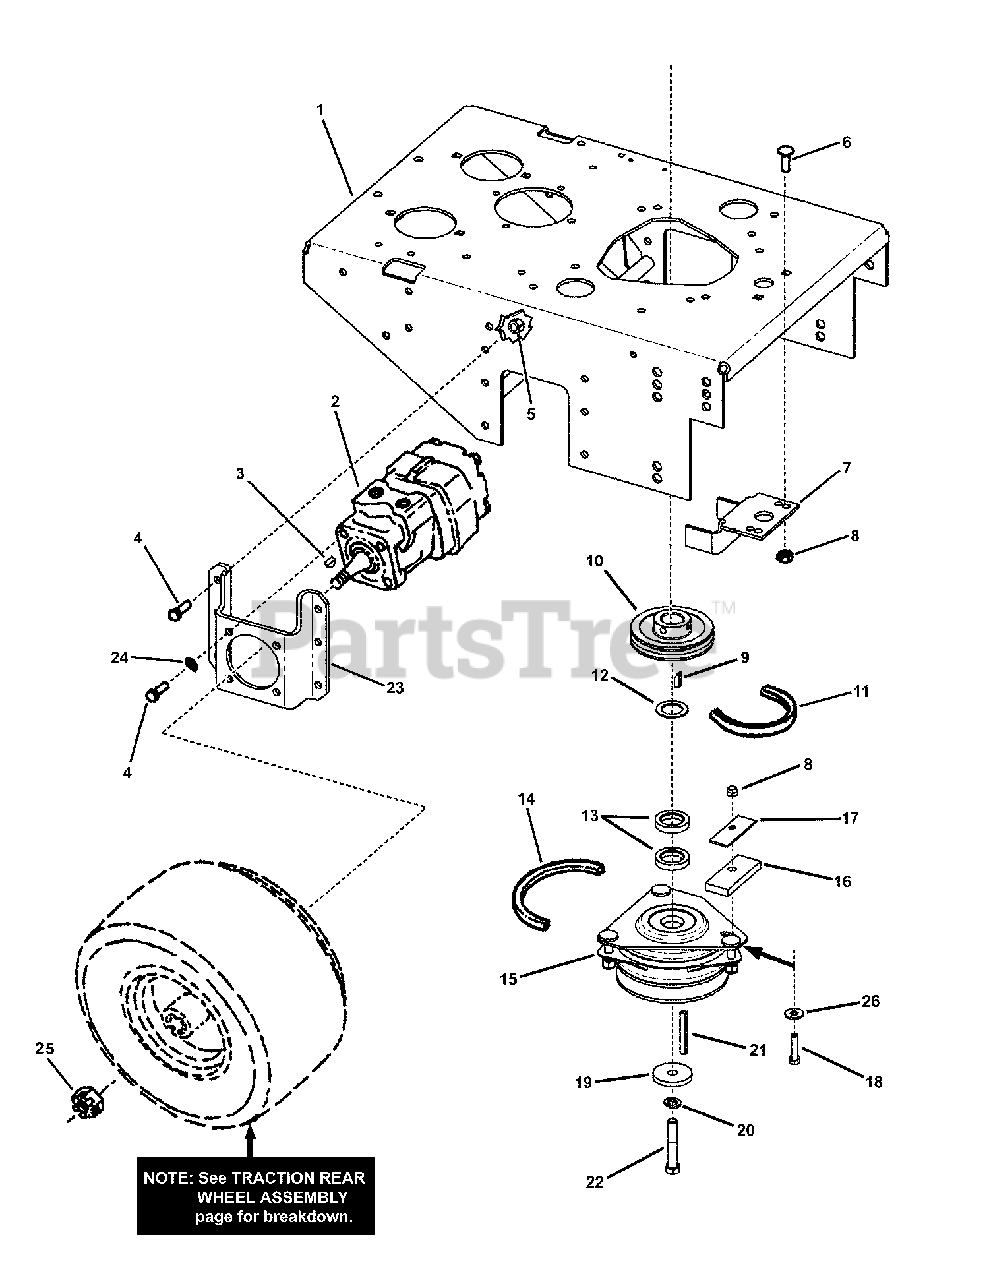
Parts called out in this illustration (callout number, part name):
1	DECK, Rear (Weldment)
2	WHEEL MOTOR
3	KEY, 5/32 x 5/8" Woodruff
4	BOLT, 3/8-16 X 1" GD5 CZ
5	NUT, 3/8-16, HEX TOP LOCK
6	BOLT, 5/16-18 x 1" Short Neck Carriage, GR 5
7	BRACKET, Anti-Spin
8	NUT, 5/16-18 Hex Top Lock, GR B
9	KEY, 1/4" Square w/Bevel (3/4" long)
10	PULLEY, 4", Engine/Hydro
11	V-BELT, HA4950 Engine/Hydro
12	BUSHING, 1" x 14 Ga Machine
13	SPACER,Clutch, Ogura
14	*V-BELT, Sect HB, Nom. Effective Length: 84.80" (Engine/Deck belt)
14	*V-BELT, Sect HB, Nom. Effective Length: 66.00" (Primary Engine/Deck belt)
14	*V-BELT, Sect HB, Nom. Effective Length: 67.80" (Engine/Deck belt)
14	*V-BELT, Sect HB, Nom. Effective Length: 74.00" (Primary Engine/Deck belt)
15	**CLUTCH, Electric (Ogura model GT2.5 SN01)
16	BUMPER, Electric Clutch
17	WASHER, Rectangular Steel
18	BOLT, 5/16-18 X 1-1/4 GD5 YZ
19	SPACER, Clutch
20	WASHER, 7/16" Split Lock
21	KEY, 1/4" Square x 2-1/4"
22	SCREW, 7/16-20 x 2-1/2" Hex Head Cap, GR 5 (w/locking patch)
23	BRACKET, Wheel, Hydro Gear
24	WASHER, 3/8" SPLIT LOCK
25	NUT, 3/4-20 Hex Castle
26	WASHER, .375 I.D. x .875 O.D. Flat
